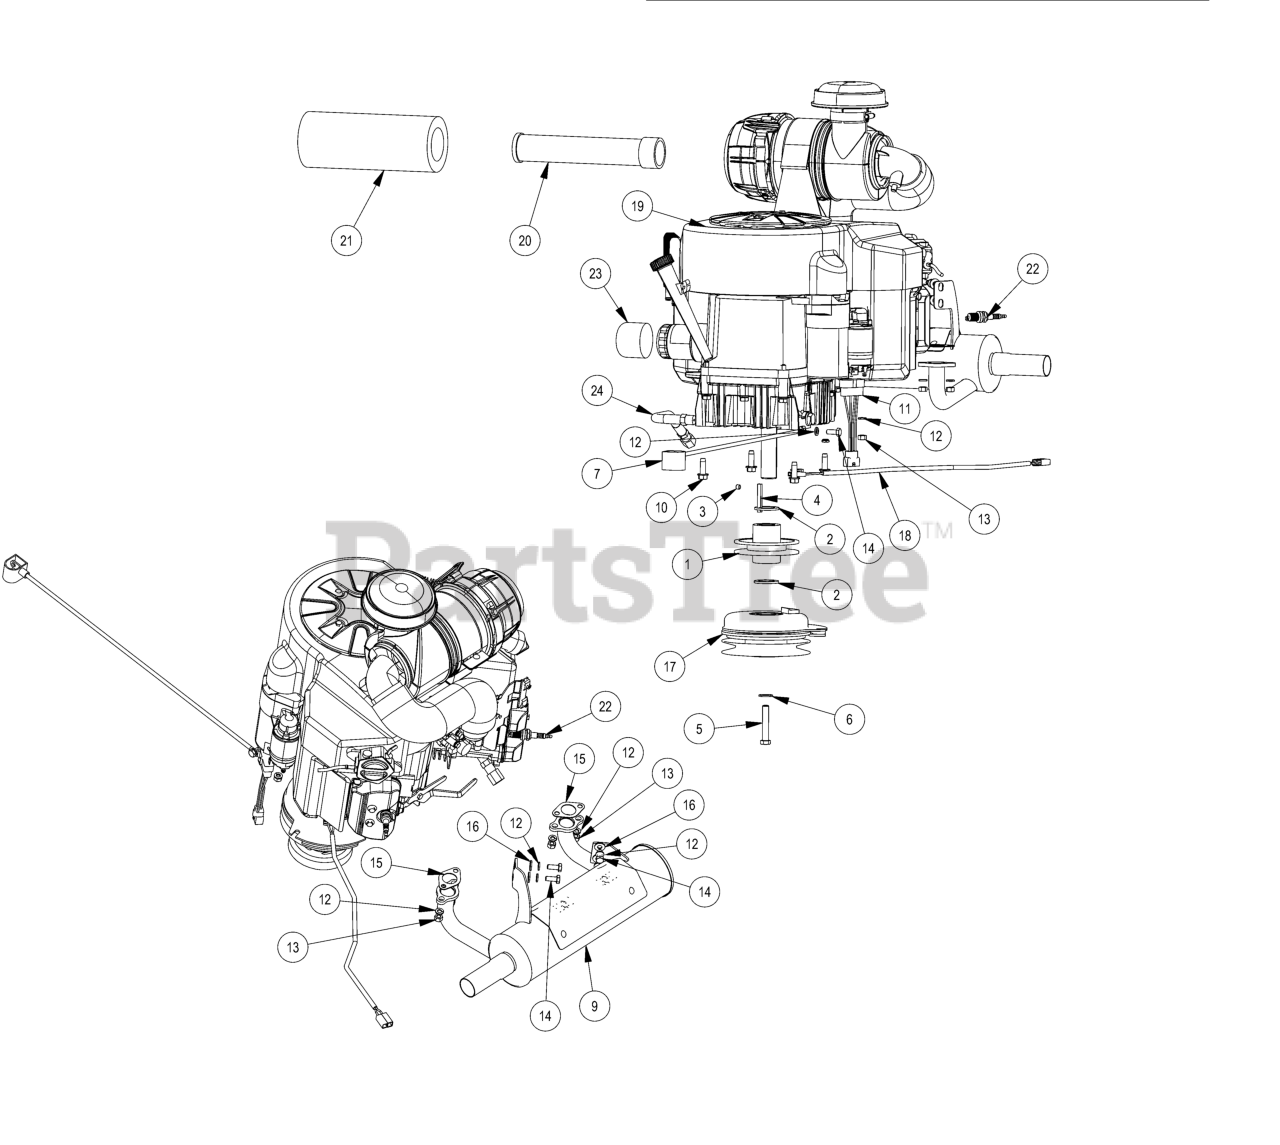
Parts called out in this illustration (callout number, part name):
1	4 3/4 Motor Pulley
2	1.140 ID X 1.750 OD X .132 THICK FLAT WASHER PLAIN
3	5/16-24 X 1/4 SOCKET SET SCREW (CUP PT) PLAIN
4	1/4 X 2 SQ MACHINERY KEY 1018 STL PLAIN
5	7/16-20 X 2-1/2 HEX CAP SCREW (GR.8) ZINC YELLOW
6	3/8 FLAT WASHER USS (1" OD) ZINC
7	24 inch Black Cable – MZ/ZT
8	5/16-18 NYLON INSERT JAM LOCKNUT ZINC
9	Revolt Kawasaki FX850 Exhaust
10	3/8-16 X 1-1/8 HEX WASHER UNSLOT SERRATED (TRI-LOB) TRS ZINC YELLOW
11	2019 Harness Adaptor-Gen2 FX-ALL
12	5/16 SPLIT LOCKWASHER ZINC
13	M8-1.25 DIN 934 HEX NUT (CL.8) ZINC
14	M8-1.25 X 20MM DIN 933 HEX TAP BOLT (CL 8.8) ZINC
15	Exhaust Gasket
16	1/4 USS FLAT WASHER (3/4 OD) ZINC
17	Clutch Assembly
18	Clutch Pigtail
19	Kawasaki Engine FX-850-V-CS09R
20	Inner Air Filter
21	Outter Air Filter
22	Spark Plug - Kawasaki
23	Oil Filter
24	Oil drain Hose
